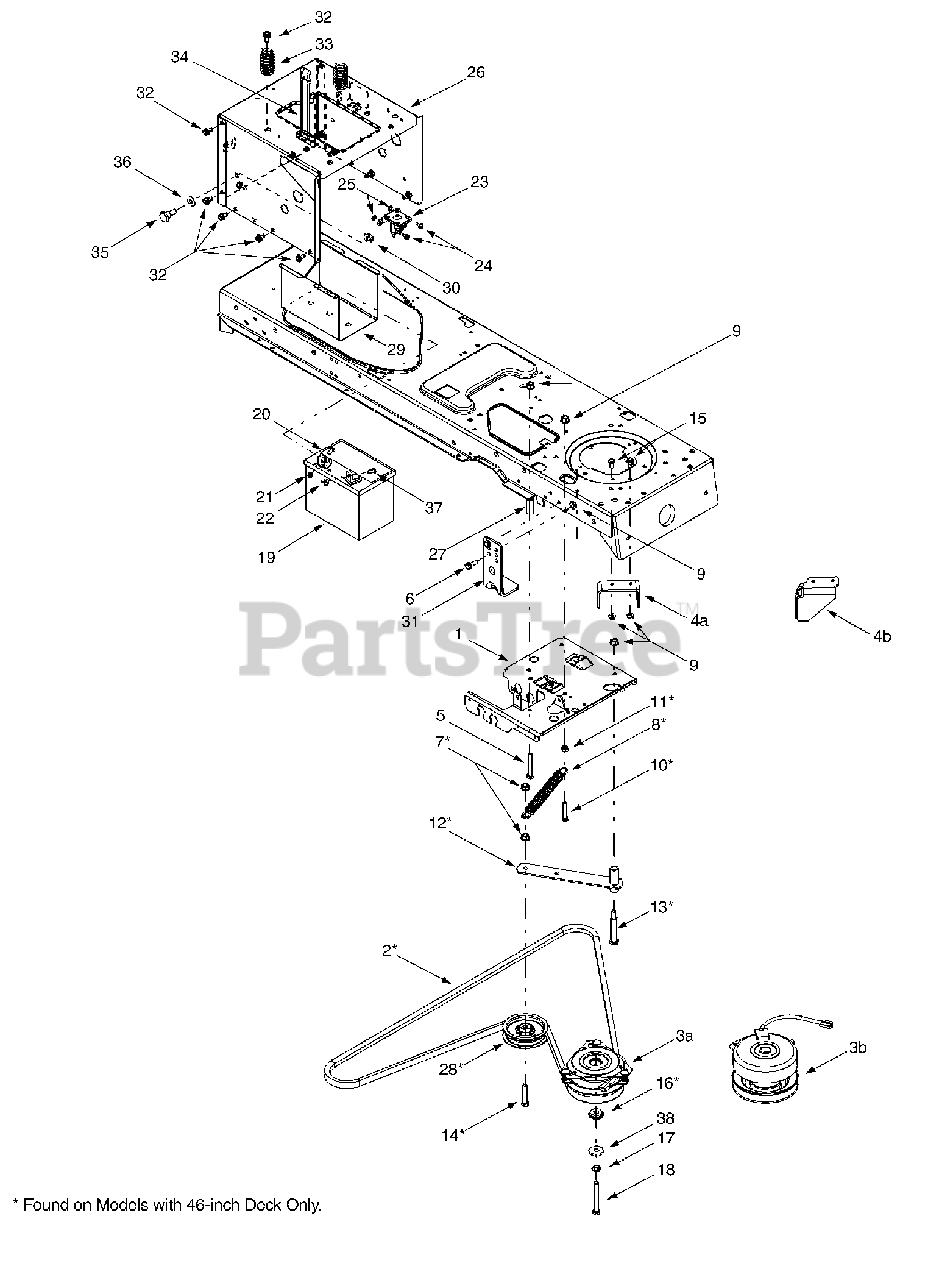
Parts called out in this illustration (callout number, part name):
2	PTO Belt (Models w/ 46-inch Deck)
2	PTO Belt (Models w/ 54-inch Deck)
3A	Electric PTO Clutch (Models w/ 46-inch Deck)
3B	Electric PTO Clutch (Models w/ 54-inch Deck)
6	Hex Head Washer Screw, 5/16-18 x .875
7	Flange Lock Nut, 3/8-16
8	Extension Spring, .62 x 5.62
9	Flange Lock Nut, 5/16-18
10	Hex Cap Screw, 5/16-18 x 1.75
11	Hex Nut, 5/16-18
14	Hex Cap Screw, 3/8-16 x 2.0
15	Hex Cap Screw, 5/16-18 x .625
16	Shoulder Spacer, 1.38 x .445 x .36
17	Lock Washer, 7/16
18	Hex Cap Screw, 7/16-20 x 3.25 (Grade 5)
19	12-volt Battery, 270 CCA
20	Hex Cap Screw, 1/4-20 x .62
21	Hex Sems Nut, 1/4-20
22	Wing Nut, 1/4-20
23	Solenoid, 12-Volt, 100 Amp
24	Self Tapping Screw, 1/4-20 x .5
25	Lock Washer, 1/4
28	Idler Pulley, 3.5
32	Self Tapping Screw, 5/16-18 x .625
33	Compression Spring, 1.28 x 3.5
34	Battery Strap
35	Shoulder Screw, .625 x .5, 7/16-20
36	Bell Washer, .45 x 1.0 x .062
37	Shoulder Screw, 1/4-20, .25 x .15
38	Flat Washer, .45 x 1.25 x .164
